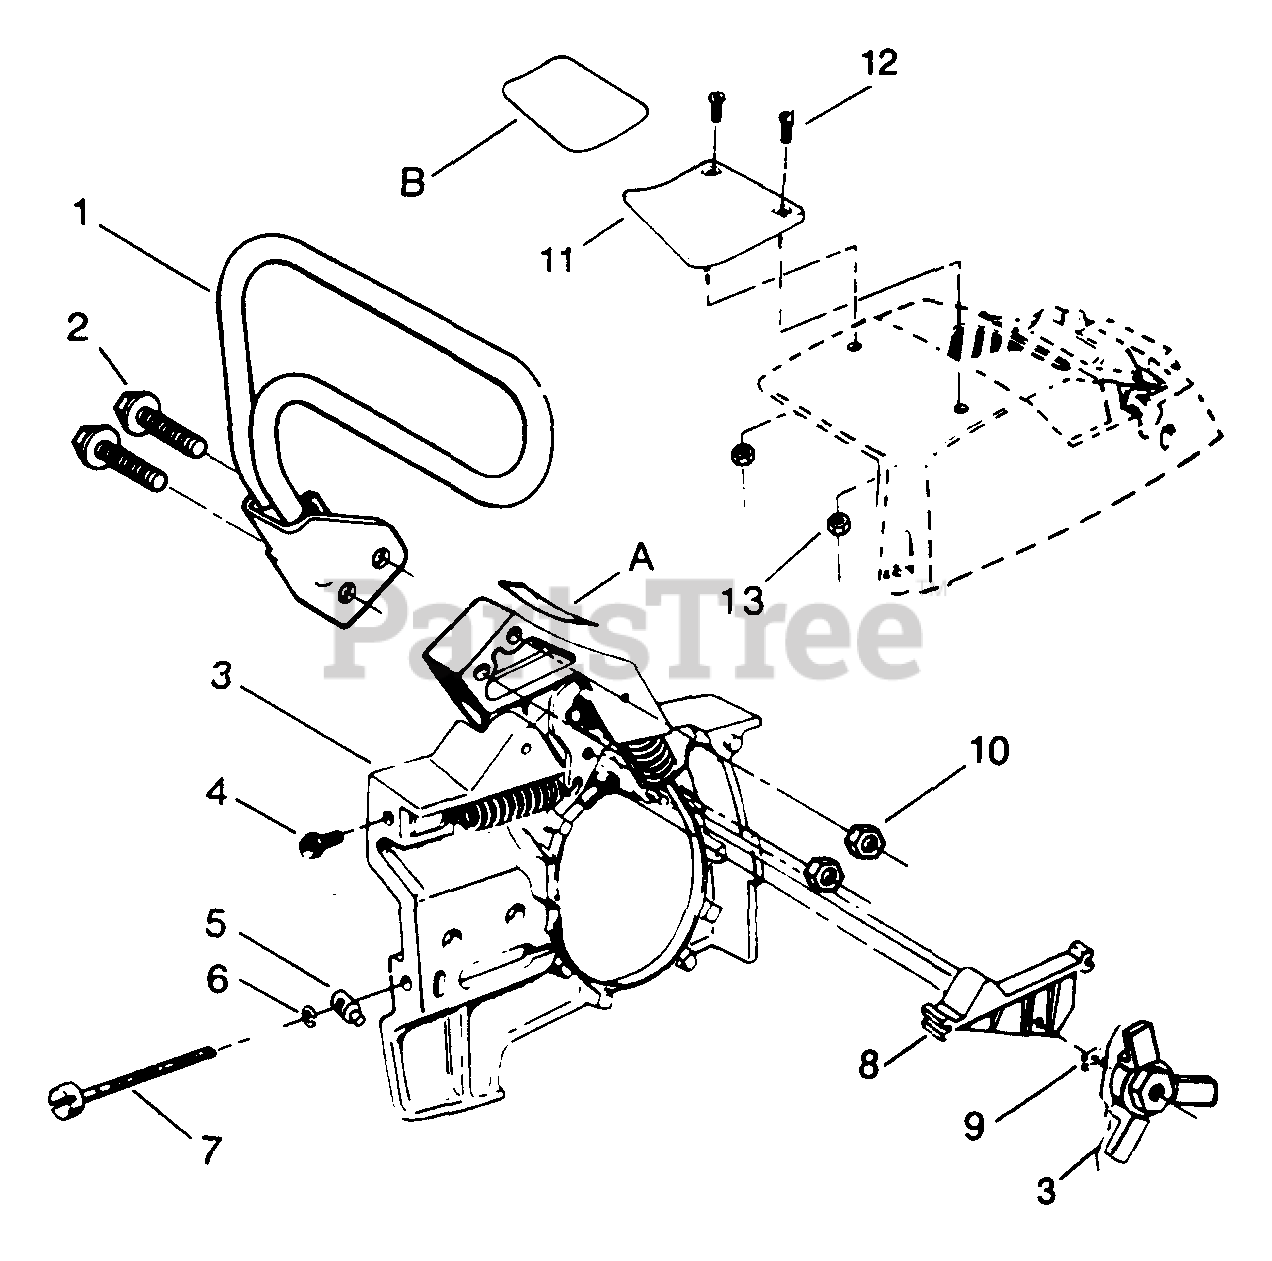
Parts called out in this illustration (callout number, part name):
1	Handle - Actuating Arm
2	Screw - Handle
3	Spider - Clutch
4	Screw - Adjusting
5	Nut - Bar Adjusting
6	"E" Ring
7	Screw - Bar Adjusting
9	Retaining Ring
10	Nut - #10-24
11	Shield - Heat
12	Screw - #10-24 x 1/2
13	Nut - #10-24
A	Decal - Warning
B	Decal - Instruction
